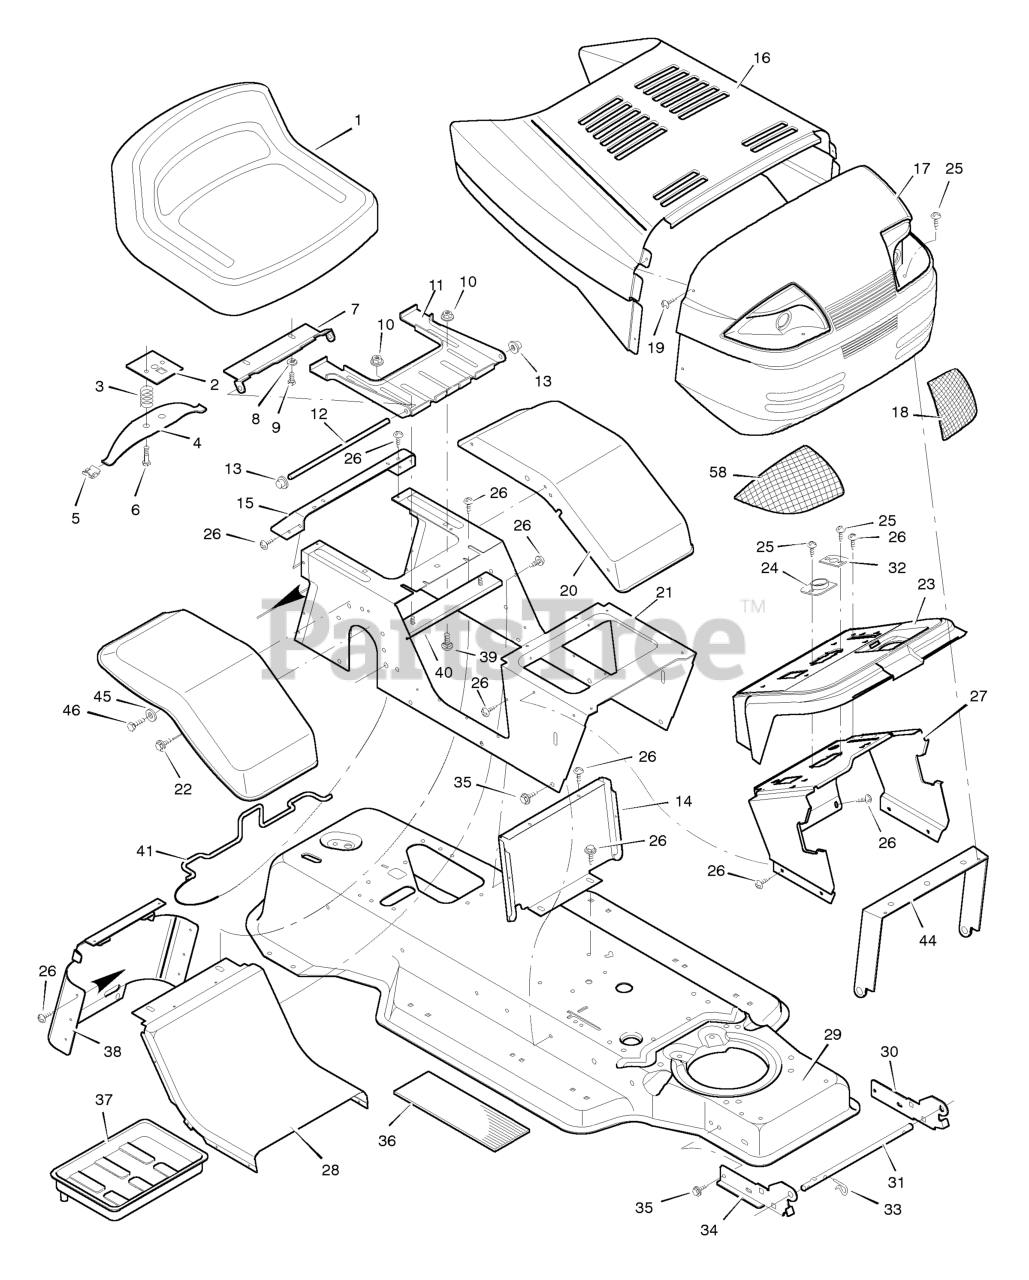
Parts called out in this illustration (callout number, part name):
2	Plate Assembly, Switch
3	Spring, Compression
4	Spring, Seat
5	Glide, Spring
6	Bolt, Shoulder
7	Support, Seat
8	Lockwasher
9	Bolt, Hex
10	Locknut, Flange
11	Bracket, Pivot
12	Rod, Pivot
13	Cap, Push On
14	Insert, Front
15	Fender, Apron
17	Grille Assembly
18	Lens, Left
21	Console Assembly
23	Dash Panel
24	Bearing, Steering
26	Screw
27	Support, Dash
28	Insert, Rear
29	Frame Assembly
30	Bracket, Left Grille
31	Rod, Pivot
32	Bearing
33	Pin, Hair
34	Bracket, Right Grille
37	Tray, Battery
38	Cap, Console
39	Bolt
40	Channel Assembly
41	Clamp, Battery
44	Brace, Grille
45	Washer
46	Bolt, Hex
58	Lens, Right
